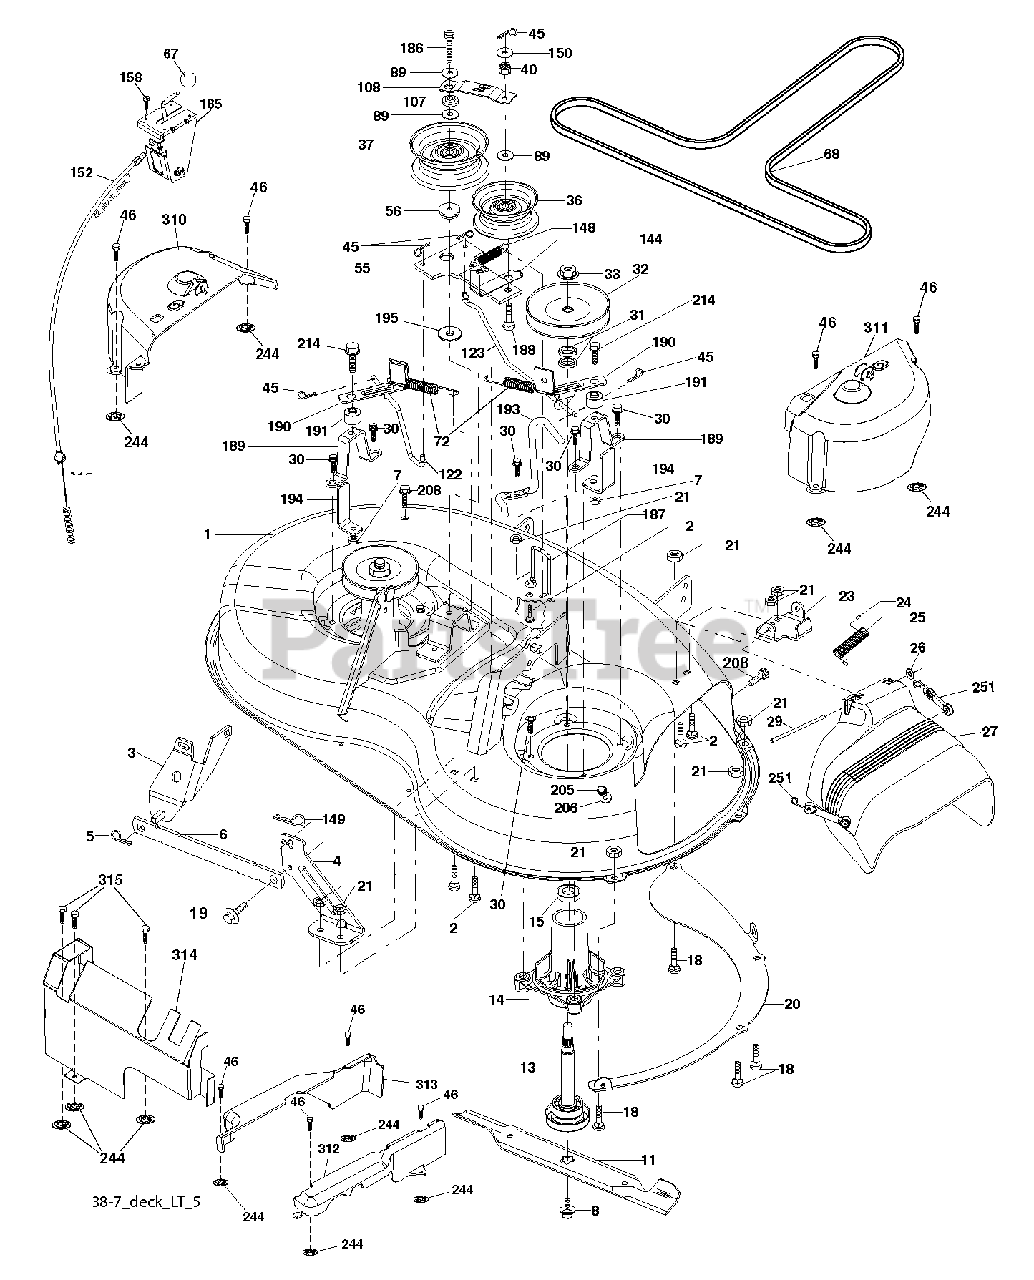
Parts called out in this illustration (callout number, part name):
1	DECK SVC 38/94 192556X431
2	BOLT 5/16-18 X3/4 ZN/YEL GR 5
3	BRKT ASM SWAY BAR
4	BRACKET DECK SWAY BAR 38"/42"
5	Retainer Spring
6	BAR SWAY DECK
7	NUT.71038.31-18.HEX.NYLOCK
8	BOLT.WASHER.ASM.7/16-2
11	BLADE 38" PREMIUM
13	SHAFT.ASM.MDRL.N/GREASE.38
14	HOUSING.MANDREL.4PT.
18	BOLT
19	BOLT SHD 5/16-18
20	BAFFLE.VORTEX.FRONT.38"
21	LOCKNUT
23	BRKT.DEFLECTOR.38"2005+
24	CAP-SLEEVE LT
25	SPRING.TORSION.DEFLECT
26	NUT PUSH M
27	SHIELD ASM.DFLCTR MWR.38-7"BLK
29	ROD.HINGE
30	SCREW, WASHER HEAD
31	WASHER.SPACER.MANDREL
32	PULLEY MANDREL
33	NUT.FLANGE.LOCK.TOP
36	FLAT IDLER PULLEY
37	PULLEY.IDLER.FLAT.UNPLATED
45	RETAINER M
46	SCREW.1/4-20X5/8
56	SPACER.RETAINER.MOWER
67	KNOB T (3/8 HOLE)
68	V-BELT.MOWER.38"2005+
72	SPRING.BRAKE.RETURN.38"
89	WASHER
107	SPACER.IDLER.ARM
108	STIFFENER.IDLER.ARM
122	LINK.BRAKE.38"LEFT.2007
123	LINK.BRAKE.38"RIGHT
144	KEEPER BELT
148	IDLER RETURN SPRING
149	SPRING.RETAINER.YELLOW.ZINC
152	CABLE.CLUTCH.38".SERVICE
158	SCREW
185	HEAD ASM. CABLE CLUTCH
186	SCREW.HXWSH.3/8
187	KEEPER BELT
188	BOLT, CARRIAGE IDLER
189	STAND, BRAKE
190	ARM, BRAKE
191	BRAKE.SPACER.38".DECK
193	KEEPER BELT RH MANDREL
194	GUARD BRAKE
195	WASHER 12/32X2X10GA
205	SCREW
208	SCREW 3/8-16X1/2
214	BOLT/WASHER ASM 5/16-18
244	PALNUT 1/4
251	ELASTIC STRAP KIT
315	SCREW 1/4X20
